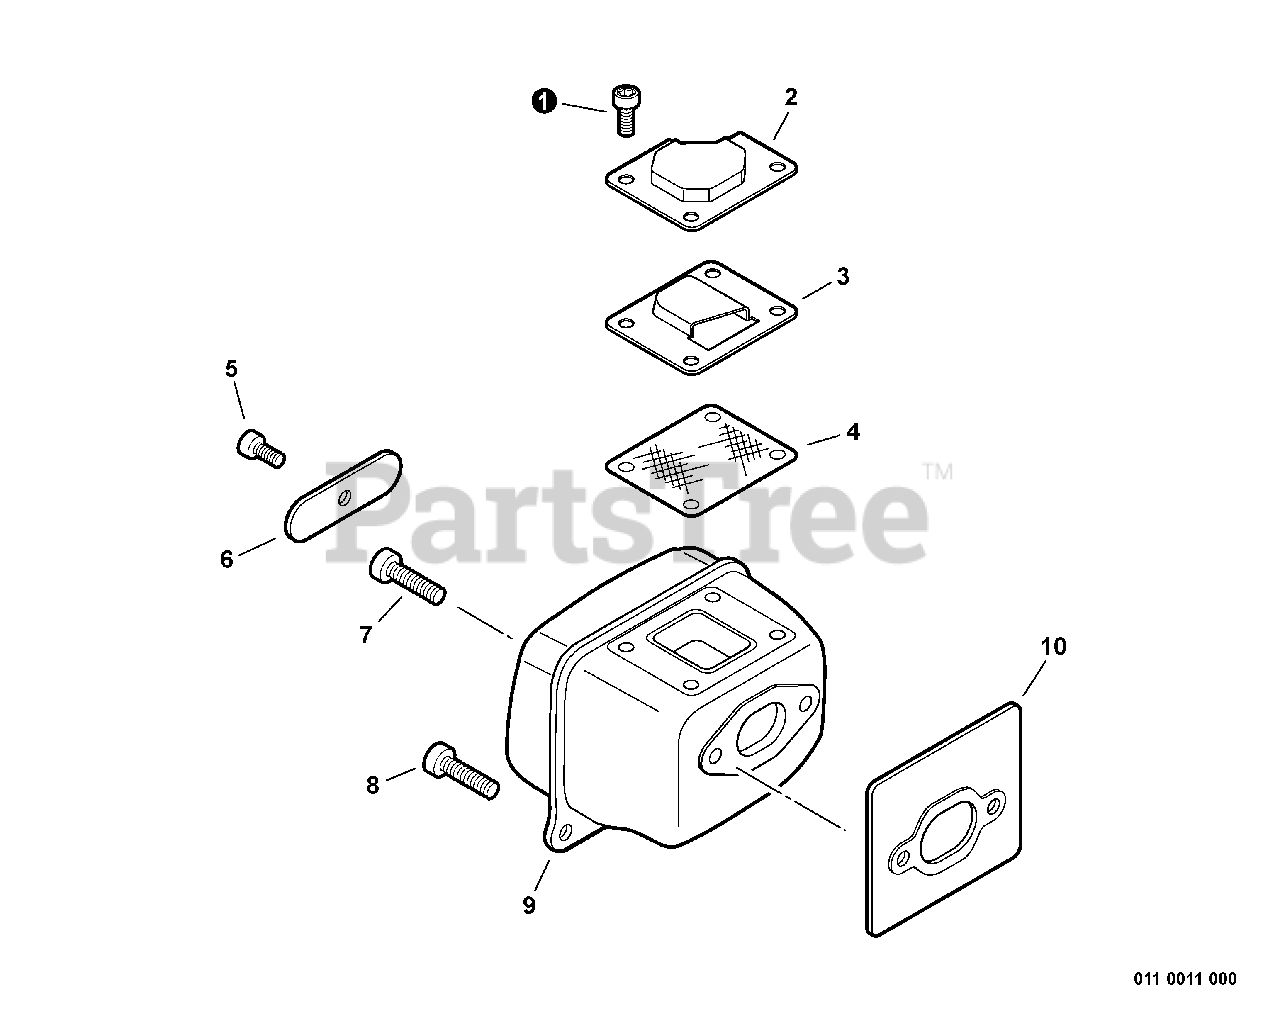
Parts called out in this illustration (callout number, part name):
1	BOLT, TORX 4×8
2	OUTLET, EXHAUST
3	GUIDE, EXHAUST
4	SCREEN, SPARK ARRESTER
5	BOLT, TORX 4×8
6	PLATE, MUFFLER
7	BOLT, TORX 5×20
8	BOLT, TORX 5×20
9	MUFFLER
10	GASKET, EXHAUST
